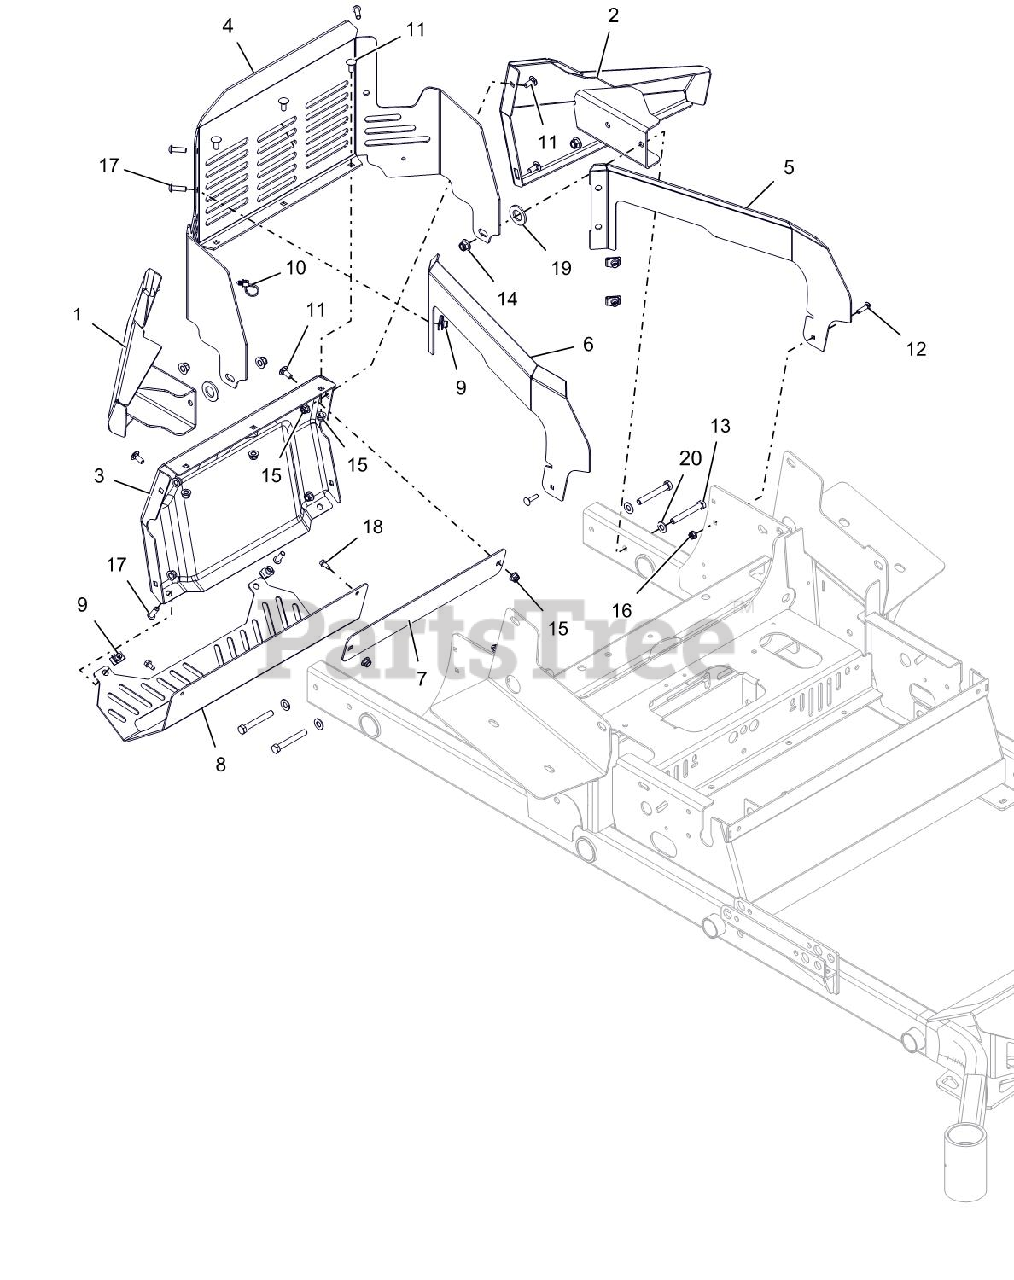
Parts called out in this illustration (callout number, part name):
1	WMT,RH REAR BMPR WING W/DECAL
2	WMT,LH REAR BMPR WING W/DECAL
3	PT200/400 REAR BUMPER - BLACK
4	PT400 ENGINE GUARD - BLACK
5	HOOD STYLE TRIM (LEFT) - RED
6	HOOD STYLE TRIM (RIGHT) - RED
7	BACKER PLATE - RED
8	PT200/400 MUFFLER GUARD - BLK
9	NUT-CLIP RETAINER 5/16-18X.56
10	CABLE TIE W/ TREE (.25 HOLE)
11	@BLT-RDHDSQNK .31-18X.75 G5YZ
12	@BLT-RDHDSQNK .25-20X1.00 G5YZ
13	@BLT-HEX .38-16X2.75 GR5 YWZC
14	@NUT-LK-NYL-FLG .38-16 YWZC
15	@NUT-LK-NYL-FLG .31-18 YWZC
16	@NUT-LK-NYL-FLG .25-20 YWZC
17	SCR-SKH .31-18X1.0 BTNHD YWZC
18	SCR-TAP .25-20X.50 HWH TR YWZ
19	@WSHR-FL-STL.812X1.50X.135YWZC
20	@WSHR-FL-STL.406X.812X.065 YWZ
